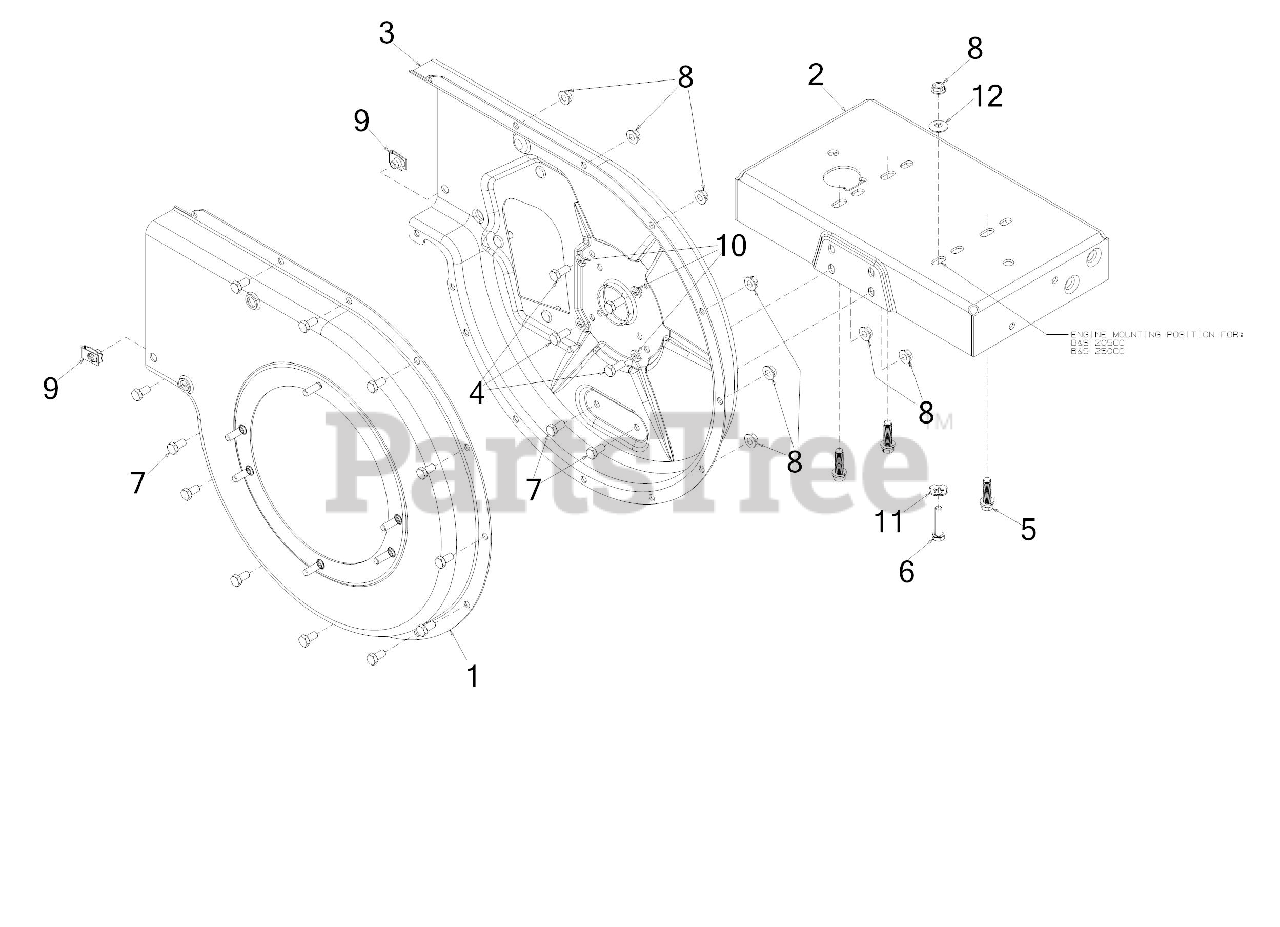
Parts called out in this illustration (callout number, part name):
1	FLAIL HOUSING ASSEMBLY
2	FRAME ASSEMBLY
3	INNER FLAIL HOUSING
4	HEX SCREW 5/16-24 x .75
5	SCREW 3/8-16 x 1.250
6	SCREW 5/16-18 x 1.5 LG
7	SCREW 5/16-18X .625 GR5
8	HEX FLANGE NUT
9	U-NUT
10	LOCK WASHER 5/16
11	SPECIAL WASHER
12	BELL WASHER .337 X.867 x .057
